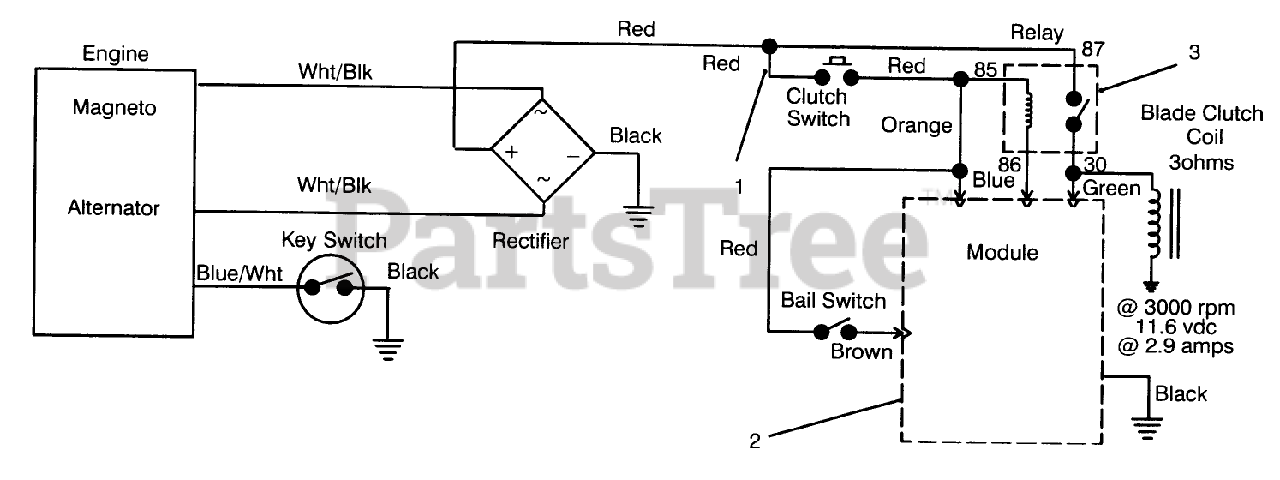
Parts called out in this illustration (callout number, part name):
1	Wire Harness
2	Module
3	RELAY
